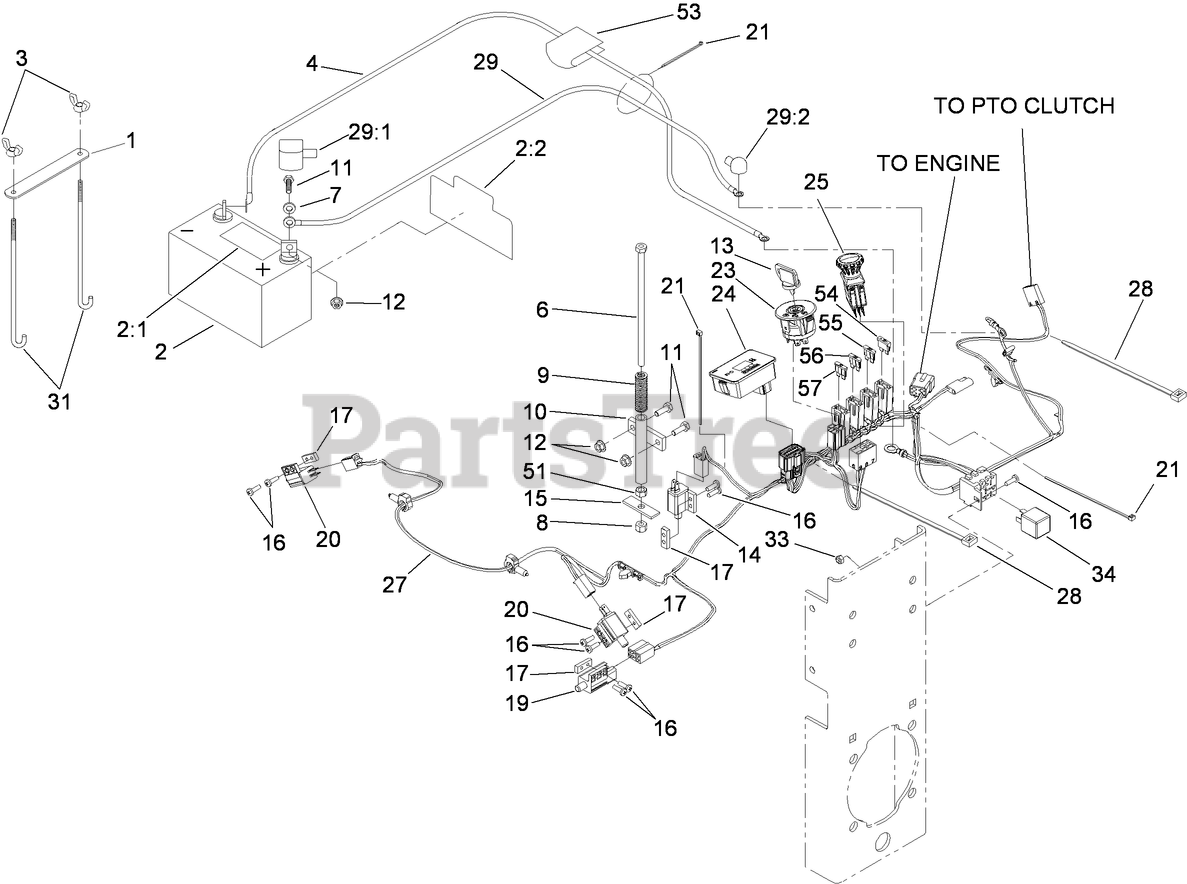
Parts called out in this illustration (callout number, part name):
1	STRAP-HOLDDOWN, BATTERY
2	BATTERY
2:1	Decal-Battery
2:2	Decal-Battery
3	WINGNUT
4	WIRE-GROUND
6	SCREW-HH
7	WASHER-FLAT
8	NUT-LOCK, NI
9	SPRING-SWITCH, SEAT
10	MOUNT-SPRING, SEAT
11	SCREW-HH
12	NUT-HF
13	KEY-IGNITION
14	SWITCH-CLOSED, NORMALLY
15	PLATE-SWITCH, SEAT
16	SCREW-PPH
17	PLATE-TAPPED
19	SWITCH
20	SWITCH-OPEN, NORMALLY
21	TIE-CABLE
23	SWITCH-IGNITION
24	HOUR METER ASM
25	SWITCH-PTO, 10 AMP
27	HARNESS-ELECTRICAL
28	TIE-PLASTIC
29	POSITIVE BATTERY CABLE ASM
29:1	INSULATOR-BATTERY
29:2	INSULATOR-SOLENOID
31	BOLT-HOLDDOWN
33	NUT-LOCK, NI
51	NUT-HEX
53	DECAL-INSTRUCTIONS, CHARGING
54	FUSE-BLADE, 15 AMP
55	FUSE-BLADE, 30 AMP
56	FUSE-BLADE, 25 AMP
57	FUSE-BLADE, 10 AMP
